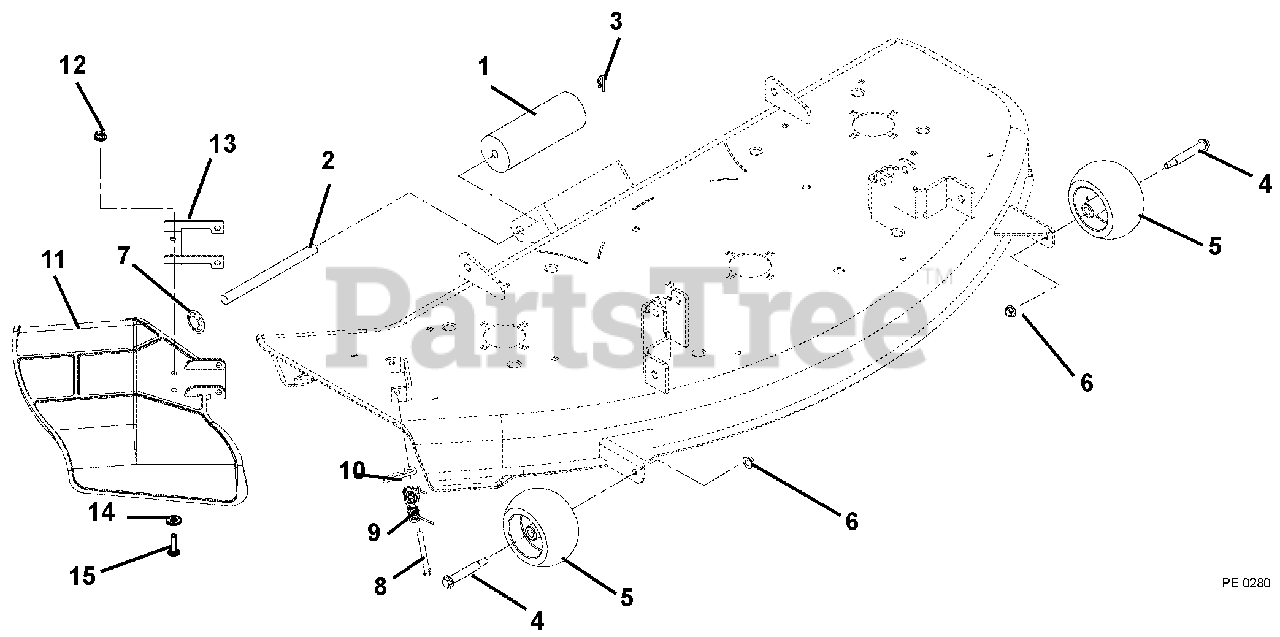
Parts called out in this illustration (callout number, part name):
1	ROLLER
2	PIN, ROLLER
3	PIN, SPRING CLIP
4	BLT-SHLDR .38-16X2.50 HWH G5
5	WHEEL 5 X 3
6	@NUT-LK-TOP-FLG .38-16 YWZC
7	PUSH NUT, .625 SHAFT
8	PIN, 5/16 X 3.88"
9	SPRING, TORSION
10	PIN-HAIR INT .08X.18X1.18 YWZC
11	MOLDED CHUTE, ZOOM
12	@NUT-LK-TOP-FLG .31-18 YWZC
13	CHUTE REINFORCEMENT
14	@WSHR-FL-STL.38X.875X.083 YWZC
15	SCR-SKH .31-18X.75 BTNHD YWZC
